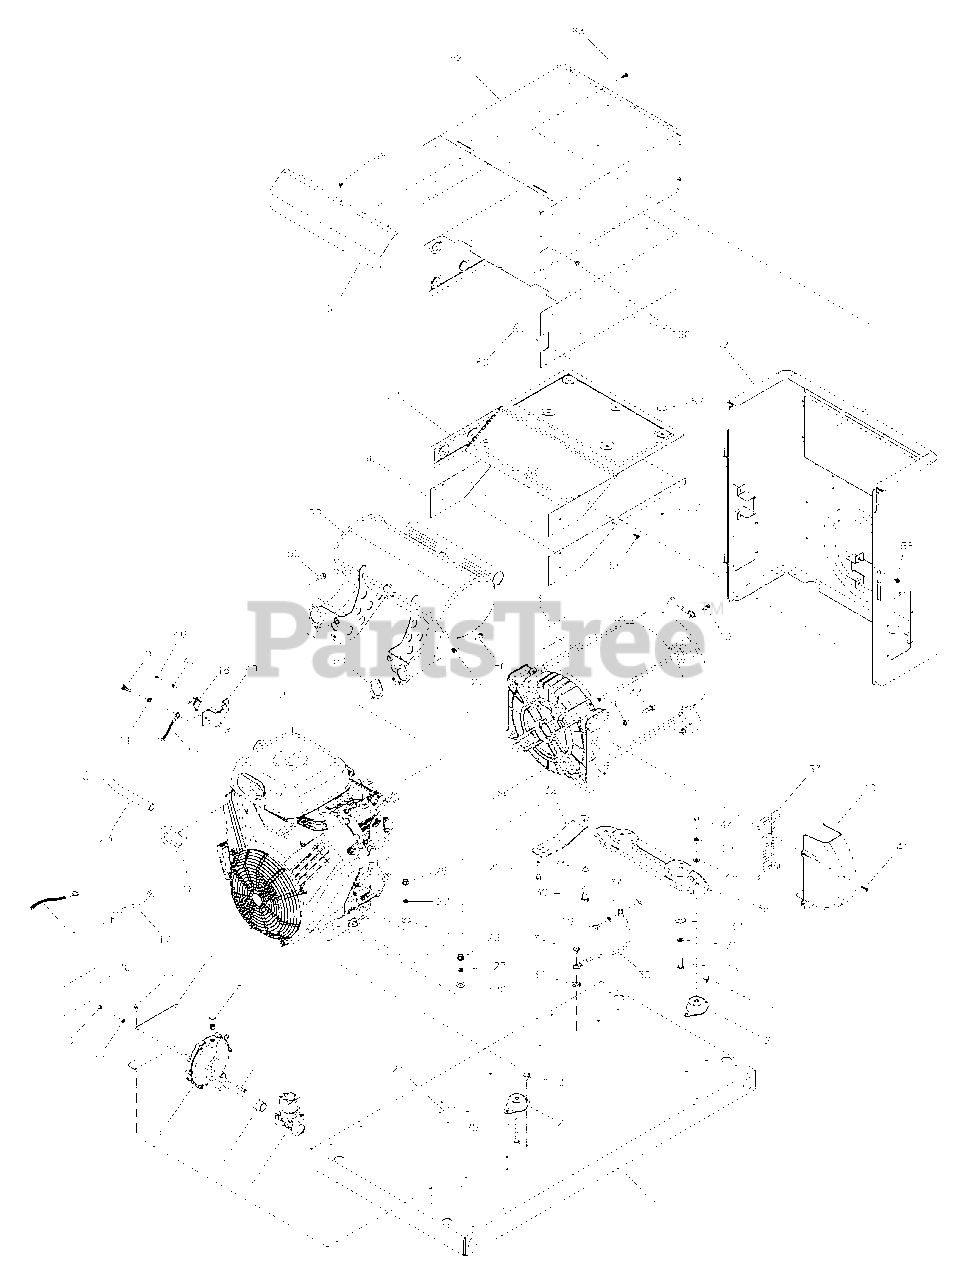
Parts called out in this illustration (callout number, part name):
1	BASE
2	MOUNT, Vibration
4	SOLENOID, Gas Fuel
6	REGULATOR, NG/LPG
7	BRACKET
9	* CAPSCREW, M6-1 x 16
10	* CAPSCREW, M6-1 x 30
11	* WASHER, Lock, 1/4
12	* NUT, M6-1
13	BOLT
15	CABLE, Battery, Black
17	CABLE, Battery, Red
18	TUBE
20	* WASHER, Flat, 5/16-M8
23	HOSE, Oil Drain
24	DECAL, Oil Drain
25	* CAPSCREW, Hex Head, 5/16-18 x 2-1/2
26	* NUT, 5/16-18
27	* WASHER, M12
29	* CAPSCREW, Hex Head, 5/16-18 x 2
30	* CAPSCREW, Hex Head, M12-1-3/4 x 35
31	* WASHER, M12
32	SUPPORT, Engine
34	* WASHER, Shakeproof, Ext, M6-1/4
36	* WASHER, Lock, 3/8
37	* WASHER, Flat, 3/8-M10
38	* CAPSCREW, Hex Head, 3/8-16 x 1
39	SUPPORT, Alternator
43	* CAPSCREW, Socket Head, 3/8-16 x 1-1/4
44	* CAPSCREW, Hex Head, 5/16-18 x 3/4
46	* SCREW, Phillips Head, 4-40 x 3/16
47	* WASHER, Lock, #4
49	PLATE, Temp Switch
50	SCREW
51	ALTERNATOR, Complete
53	DECAL
59	BULKHEAD, Alternator
62	BOX, Muffler Top
900	** ENGINE
